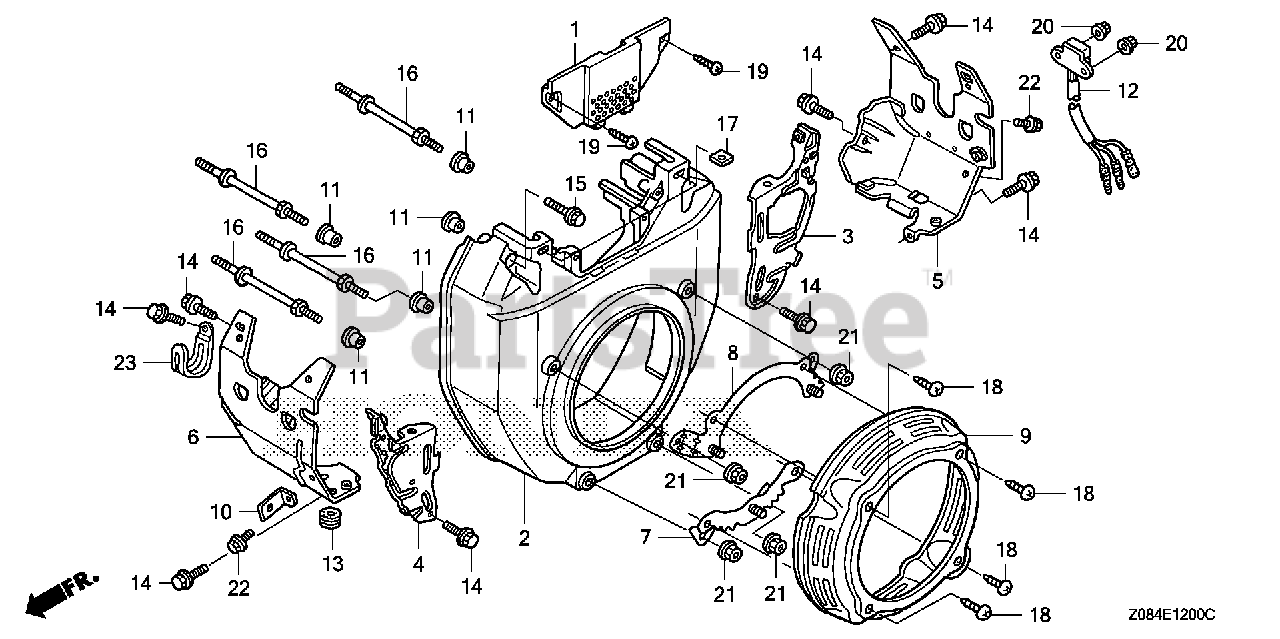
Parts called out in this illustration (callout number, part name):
1	COVER, FUEL PUMP
2	COVER, FAN *R280* (RECOIL STARTER) (POWER RED)
3	PLATE, SIDE (RR.)
4	PLATE, SIDE (FR.)
5	SHROUD (OIL ALERT)
7	STAY A, RECOIL STARTER
8	STAY B, RECOIL STARTER
9	COVER, RECOIL STARTER STAY *R280* (POWER RED)
10	BRACKET, WIRE HARNESS CLIP (H)
11	COLLAR B, TAILLIGHT
12	ALERT UNIT, OIL
13	RUBBER, RR. FENDER CUSHION
14	BOLT, FLANGE (6X12) (CT200)
15	BOLT, FLANGE (6X23) (CT200)
16	BOLT, STUD (6X71)
17	NUT, SQUARE (5MM)
18	SCREW, TAPPING (5X16)
19	SCREW, TAPPING (5X20)
20	NUT, FLANGE (5MM)
21	NUT, FLANGE (6MM)
22	BOLT, FLANGE (6X8)
23	CLIP, WIRE HARNESS
